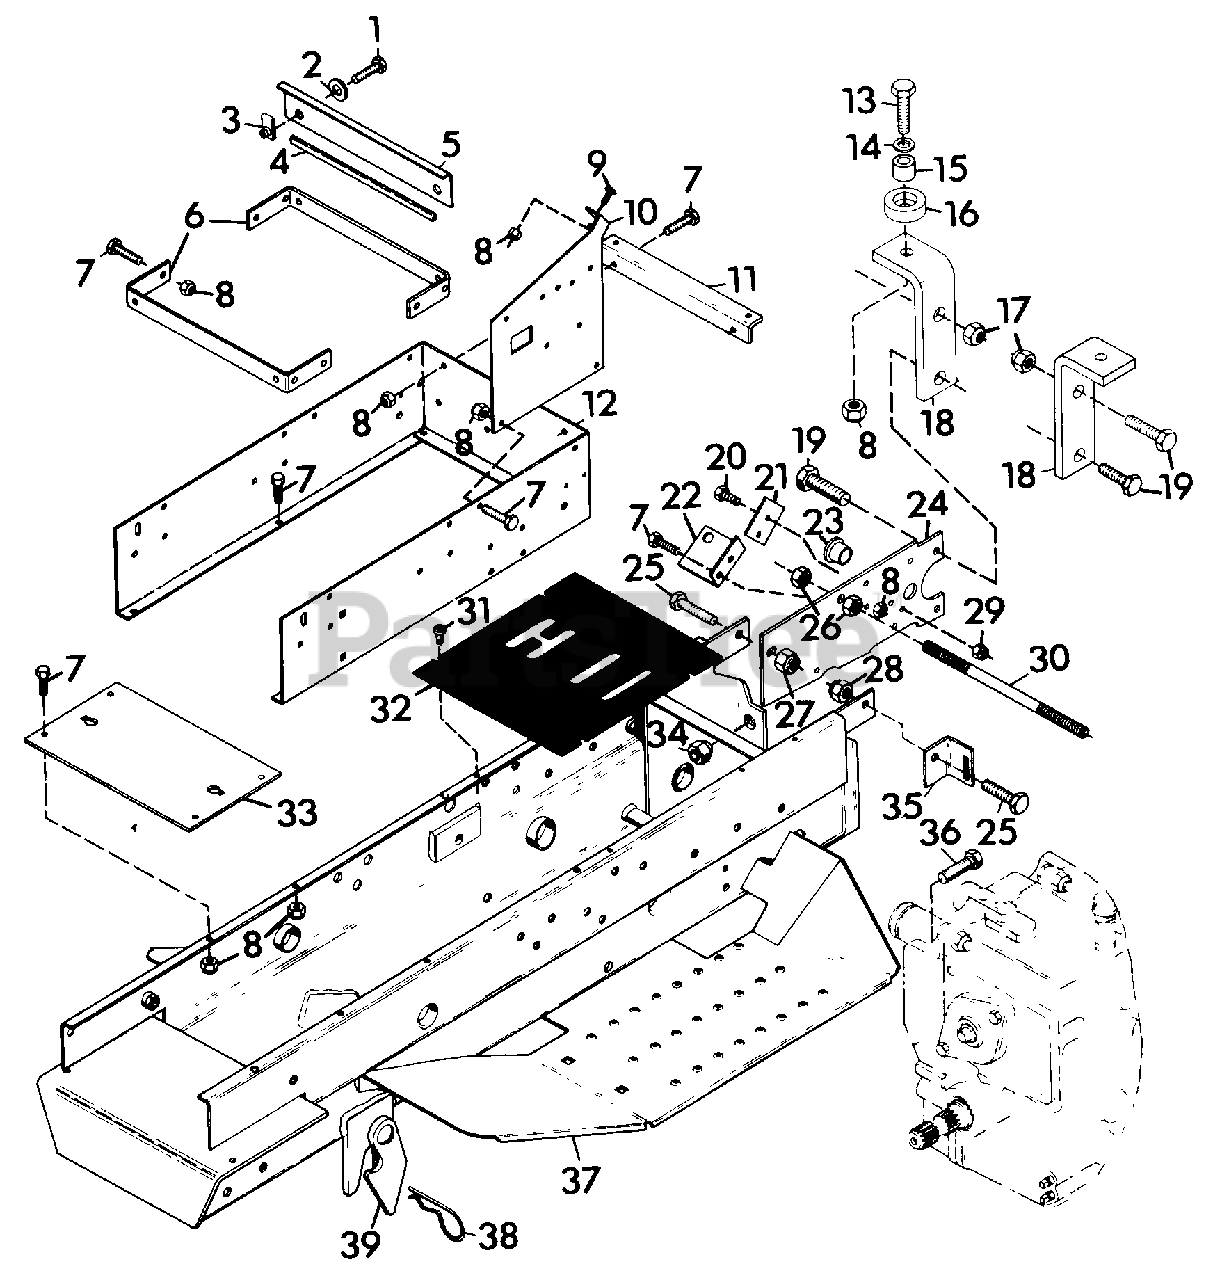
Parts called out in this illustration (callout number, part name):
1	BOLT, HEX 1/4-20X.875
2	WASHER, FLAT .281X.625X.065
3	NUT, RETAINER
4	MOULDING
5	BRACKET, FORWARD TANK
6	BRACKET, FUEL TANK
7	BOLT, HEX 1/4-20X.75
8	NUT LOCK 1/4-20
9	SCREW, MACHINE 1/4-20X.75 PAN HD.
10	BRACE, INSTRUMENT PANEL L.H.
10	BRACE, INSTRUMENT PANEL R.H.
11	BRACKET, INSTRUMENT PANEL
12	SUPPORT, INSTRUMENT PANEL
13	BOLT, HEX 1/4-20X1.25
14	WASHER, FLAT .312X.734X.065
15	BUSHING, .259X.375X.25
16	BUMPER, SEAT
17	NUT, LOCK 1/2-13
18	BRACKET, REAR HITCH
19	BOLT, HEX 1/2-13X1.50
20	BOLT, HEX 5/16-18X.75
21	BRACKET, BUSHING LOCK
22	BRACKET, INTERLOCK SWITCH
23	BUSHING, NYLON .76X1.00X.76 FLANGE
24	PLATE, FWD-REV MOUNTING
25	BOLT, HEX 3/8-16X1.25
26	NUT, HEX 1/2-13
27	NUT, LOCK 3/8-16
28	NUT, LOCK 3/8-16
29	NUT, LOCK 5/16-18
30	ROD, FRAME EXTENSION BRACE
31	SCREW, TAPPING 1/4-20X.625 PAN HD
32	PLATE, MANUAL CONTROL COVER
32	PLATE, HYDRAULIC CONTROL COVER
33	TRAY, BATTERY
34	NUT, RIM
35	BRACKET, FENDER HOLD-UP
36	BOLT, HEX 1/2-20X1.50
37	WELDMENT, 4-WHEEL FRAME
38	PIN, HAIR
39	WELDMENT, MOWER BRACKET R.H.
39	WELDMENT, MOWER BRACKET L.H.
